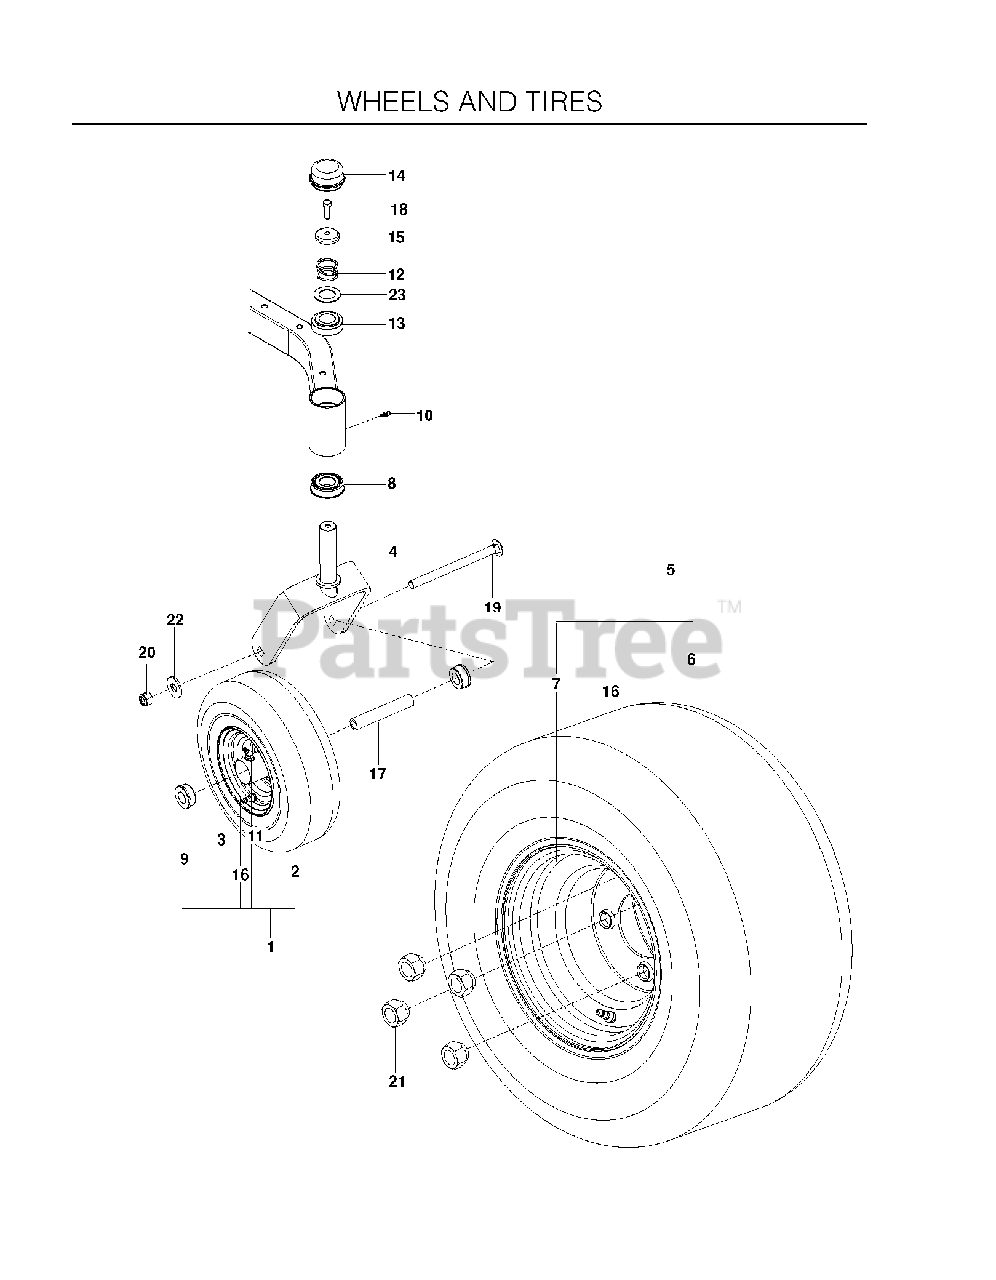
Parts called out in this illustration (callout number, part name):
1	WHEEL ASSY, WIDE, RZ
2	TIRE, 4. 10-5.4 PLY
4	YOKE, CASTER, BLUE
7	RIM 8 X 7 , W 8" OFFSET
8	BEARING FLANGED
9	BUSHING, WHEEL, 3/4"
10	ZERK, 3/16, DRIVE IN
11	ZERK
12	SPRING, CASTER
13	BUSHING, CASTER
14	GREASE CAP
15	PLUG, CASTER
16	VALVE STEM TR-412
17	SPACER, PIVOT
18	5/16-18X1 HHB G5W/NY
19	RHSNB 1/2-13 X 7.5
20	NUT 1/2-13 HEX CNTRLK GR 5 ZD
21	LUG NUT 1/2F
22	WASH USS FLAT 1/2
23	WASHER, 1.025 ID X 1.64
